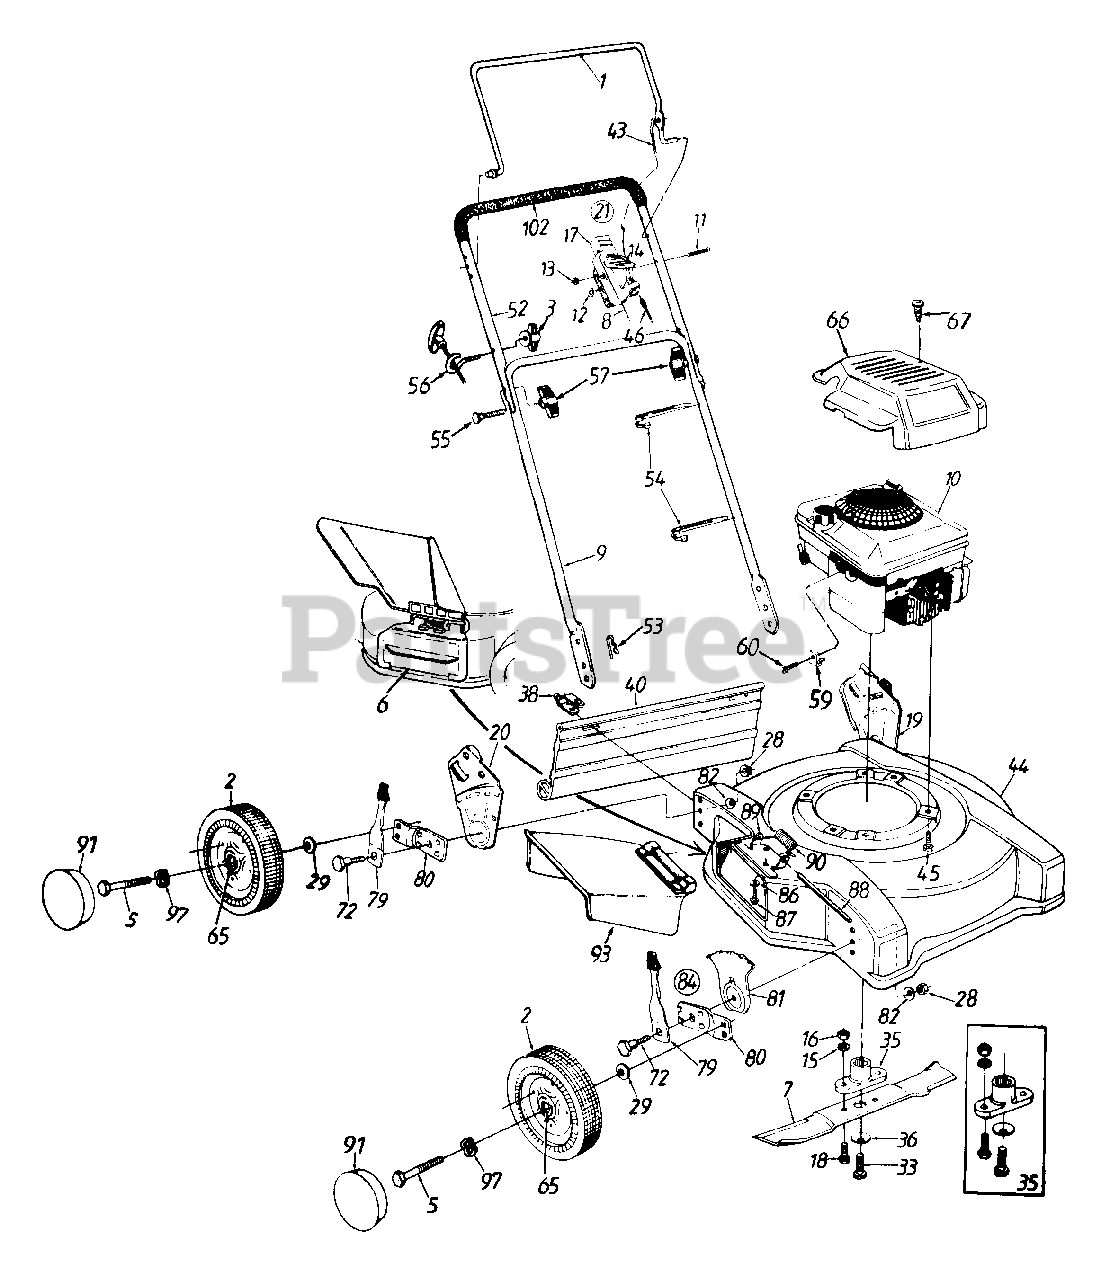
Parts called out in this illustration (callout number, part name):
2	Wheel Ass'y. Comp.
3	Wing Nut 1/4-20 Thd.
5	Axle Bolt
6	Mulching Plug
7	20" Blade
8	Throttle Control Wire - 51"
10	Engine
11	Oval C-Sunk Mach. Scr.
12	Spr. Wash..66" I.D.
13	Hex L-Nut 1/4-20 Thd.
14	Throttle Lever
15	L-Wash. 3/8" I.D.
16	Hex Nut 3/8-24 Thd.
17	Throttle Body
18	Hex Bolt 3/8-24 x 1.0" Lg.
19	Wheel Brkt. Ass'y.- L.H.
20	Wheel Brkt. Ass'y.- R.H.
21	Throttle Box Comp.
28	Hex Nut 3/8-16 Thd.
29	Bell-Wash..40" I.D. x .88"
33	Hex Bolt 7/16-20 x 1.5" Lg.
35	Blade Adapter Kit
36	Bell-Wash..46" I.D.
38	Hinge Clip
40	Rear Flap Ass'y.
44	20" Deck Ass'y.
45	Hex Wash. Hd. TT-Tap Scr. 3/8-16 x 1.00" Lg.
46	Control Cable - 39"
54	Cable Tie
55	Curved Hd Bolt 5/16-18 x 2" Lg.
56	Rope Guide
57	Hand Knob
59	Cable Clamp
60	Hex Wash. Hd. Scr #10-32 x .62" Lg.
65	Wheel Bearing
66	Engine Shroud
67	Screw #10 x 1.25" Lg.
72	Shoulder Bolt .50" Dia
79	Spring Lever Ass'y. w/Knob
81	Height Adj. Plate
82	Bell-Wash. 39" I.D. x 1.38"
84	Front Height Adj. Ass'y. Comp.- R H.
86	Bell-Wash..285" I.D. x.75" 0 D.
87	Hex Wash. Hd. Tap Scr 1/4-20 x .5" Lg.
88	Hinge Pin
89	Adapter Plate
90	Torsion Spring
91	Hub Cap
93	Chute Deflector Ass'y. Comp.
97	Wave Washer .53" I D.
102	Foam Grip
